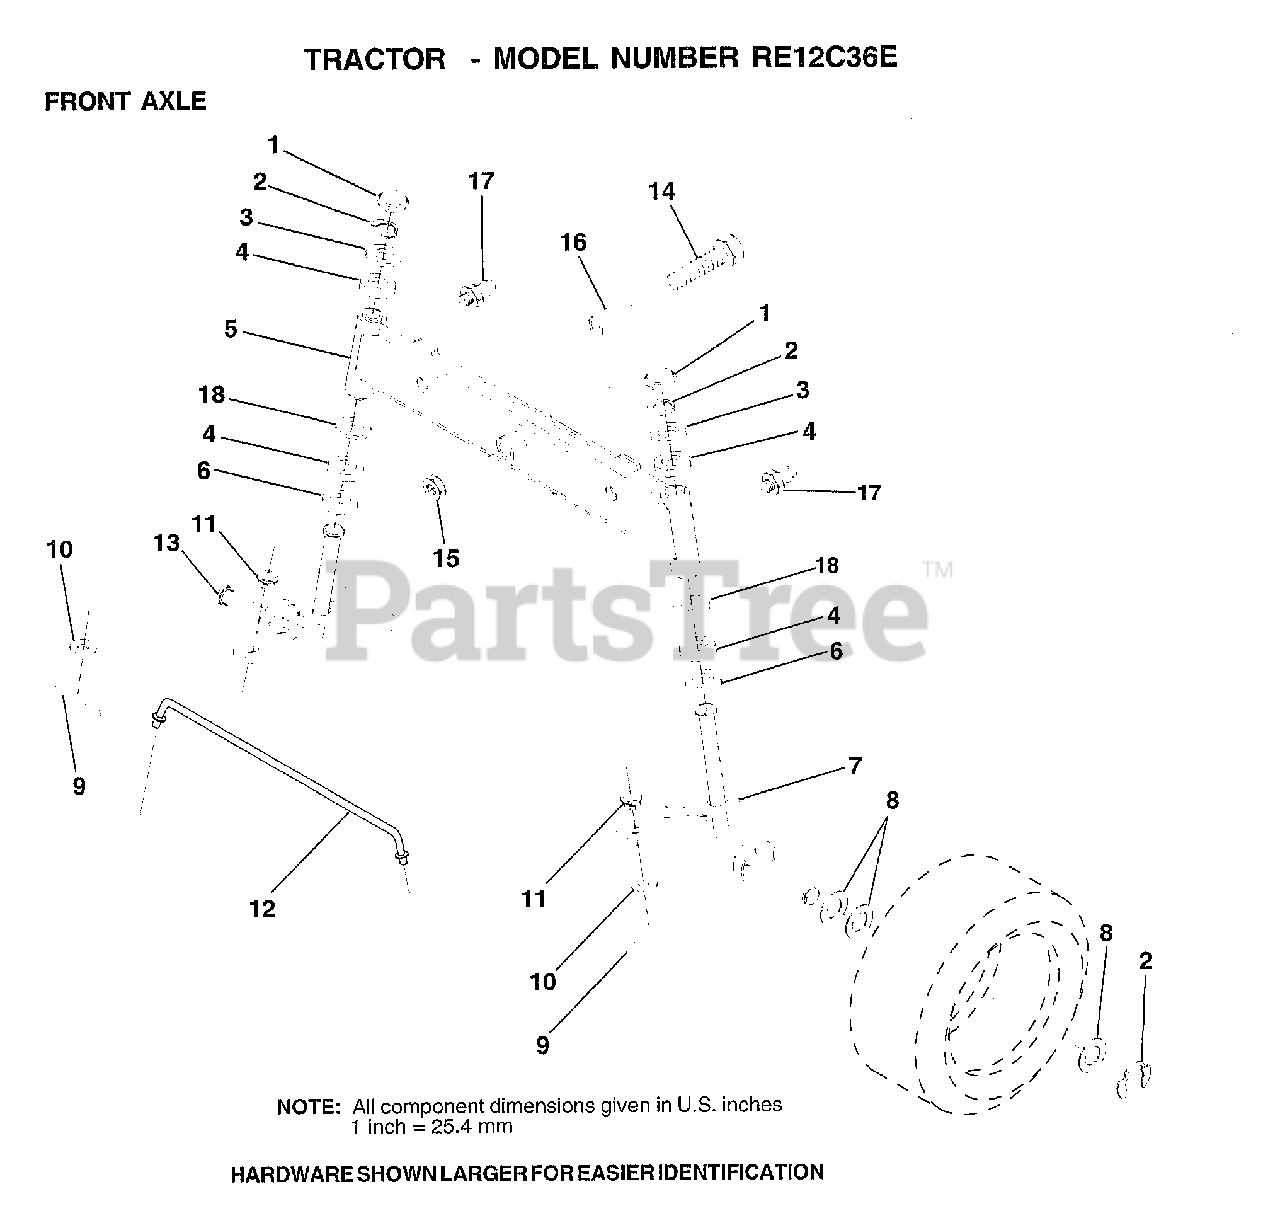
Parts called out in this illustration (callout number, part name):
1	CAP
2	RING
3	WASHER
4	COL. SRTG. BEAR.
5	AXLE ASM FRONT
6	WASHER .T
7	SPINDLE.ASSY.RH
8	WASHER
9	COTTER PIN
10	WASHER
11	BUSHING.DRAGLINK
12	TIE ROD
13	SPINDLE.ASSY.LH
14	BOLT HEX 5/8-11
15	"NUT-LOC,FLANGE LT"
16	BEARING
17	ZERK M
18	WASHER
